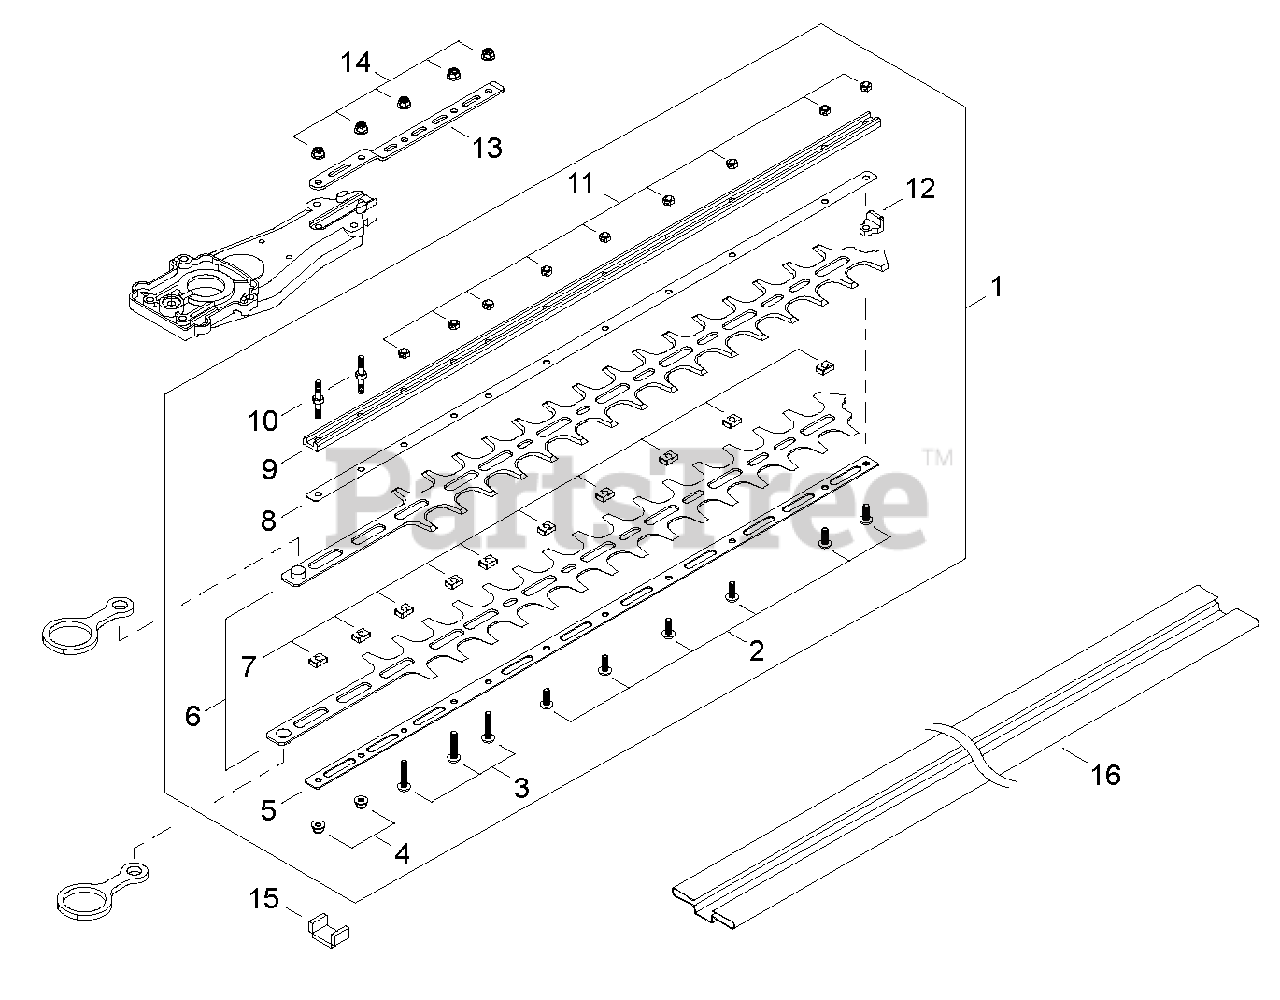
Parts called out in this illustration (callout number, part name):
1	CUTTER ASSY, 24"
2	BOLT M5×14
3	BOLT M5×25
4	NUT M5
5	PLATE, LOWER
6	BLADE, 24"
7	SPACER
8	PLATE, UPPER
9	GUIDE BAR, 24"
10	STUD, MOUNTING M5
11	NUT, LOCK M5
12	BLOCK
13	BRACKET, CUTTER
14	NUT M5
15	PACKING, FELT
16	SCABBARD 24"
